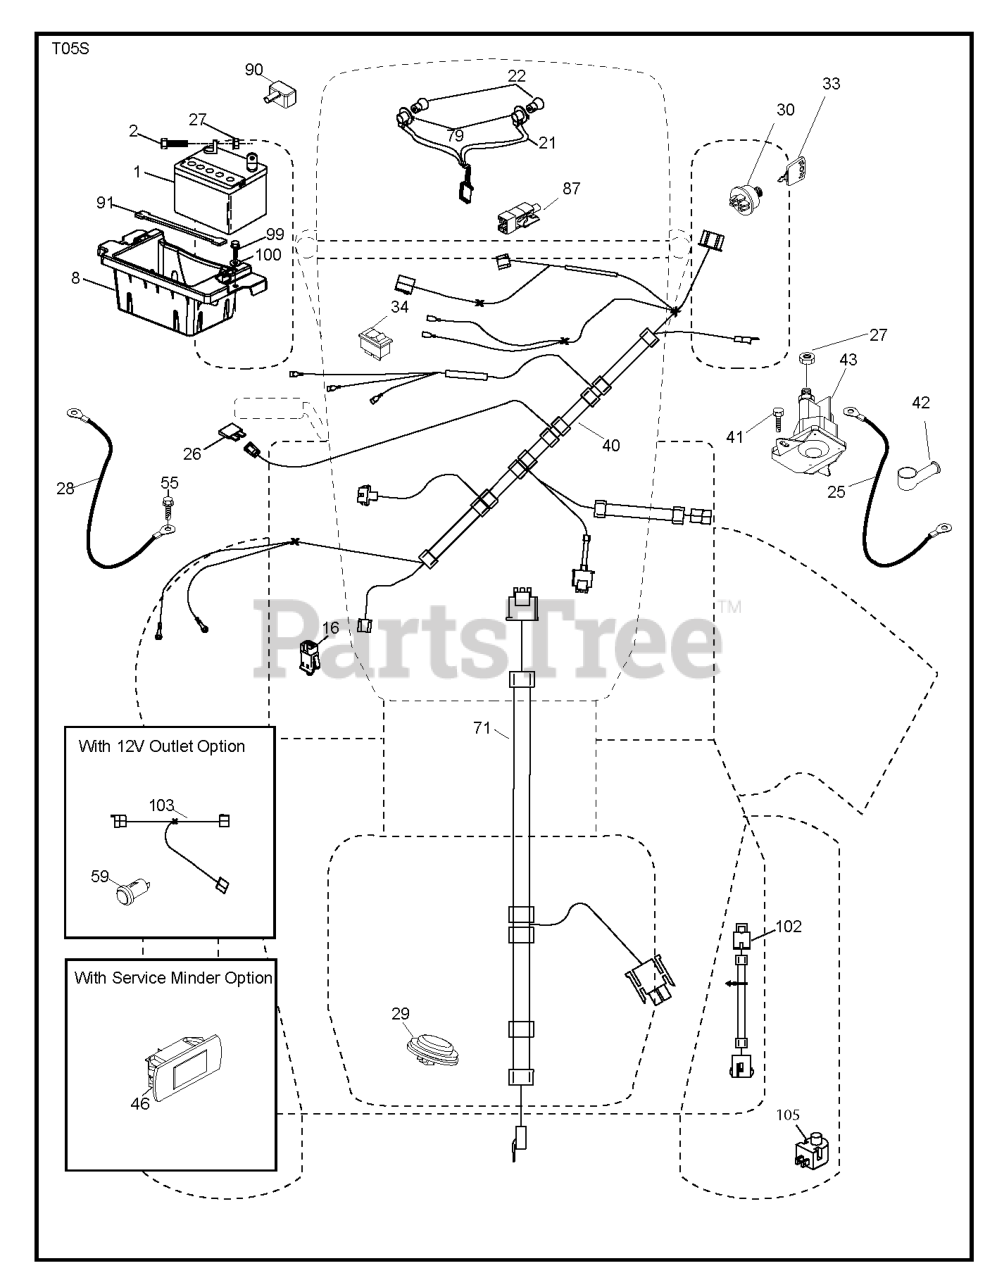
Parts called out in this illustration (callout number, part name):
1	Battery 12 Volt 25 Amp
2	BOLT.HEX.1/4.X.3/4.DICHROMATE
8	BOX BATTERY FULLY ASSEMBLED
16	SWITCH INTERLOOK PUSH-IN
21	HARNESS.LIGHT W/4152J BULBS
25	CABLE.STARTER.6G.BL/RED.17.5
26	FUSE 20AMP
27	NUT
28	CABLE GROUND 6 GA 21" 90T BLK
29	SWITCH.SEAT.DELTA.OPC.
30	SWITCH.IGN.DELTA.W.LGH.ROS
33	KEY.CHAIN.BLISTER.PACK.GEN.USA
40	HARNESS IGN. DASH
41	SCREW
42	TERMINAL COVER
43	SOLENOID.W/BRASS.PLUNGER
46	RP.GUAGE.SRVCMNDR.HRMTR.
55	SCREW 5/16"
71	HARNESS-CHASSIS SUB
79	BULB HOLDER ASM.
87	SWITCH.INTRLCK.CLUTCH.
90	COVER.TERMINAL.BATTERY
91	STRAP.BATTERY.MOUNT.FRONT(2 2)
99	SCREW HEXWSHR 1/4-20X3/4
102	HARNESS PIGTAIL PCH TEX ROS
105	REVERSE SWITCH
